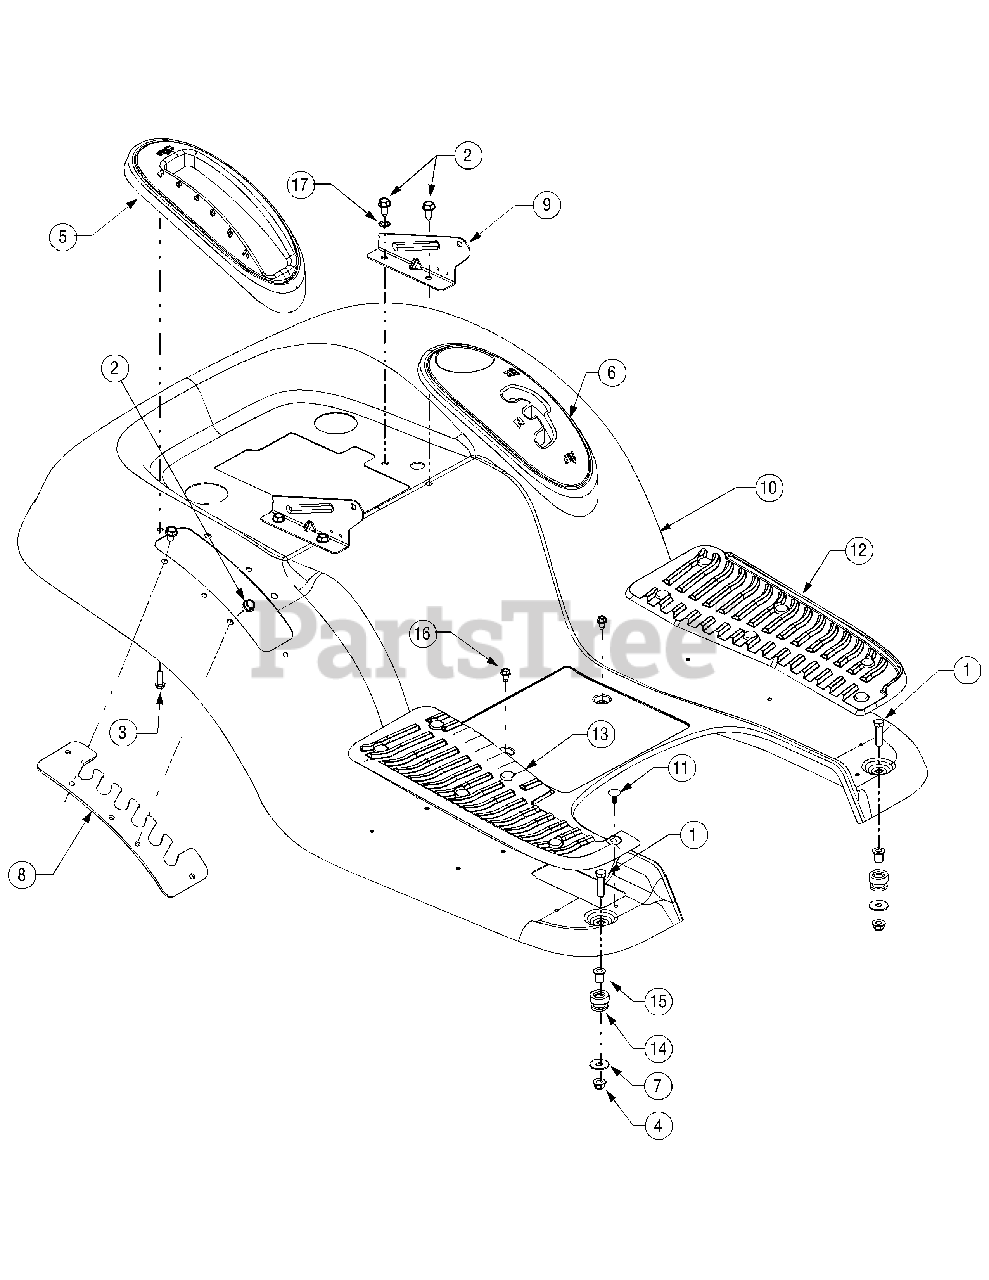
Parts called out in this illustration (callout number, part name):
1	Screw, 5/16-18 x 1.25
2	Screw, 5/16-12, 0.75
3	Screw, 1/4-15, 0.750
4	Nut, Nylon Lock, 5/16-18
5	Cover, Lift Lever
6	Cover, Cup Holder
7	Washer, Flat, .349 x 1.00 x .063
11	Clip, Ratchet, .250 Dia
12	Pad, Foot, LH
13	Pad, Foot, RH
15	Flange Spacer, .3125 x .4375 x .625
16	Screw, Self-tapping, 1/4-20, 0.500
17	Washer, Lock, 5/16 External Tooth
